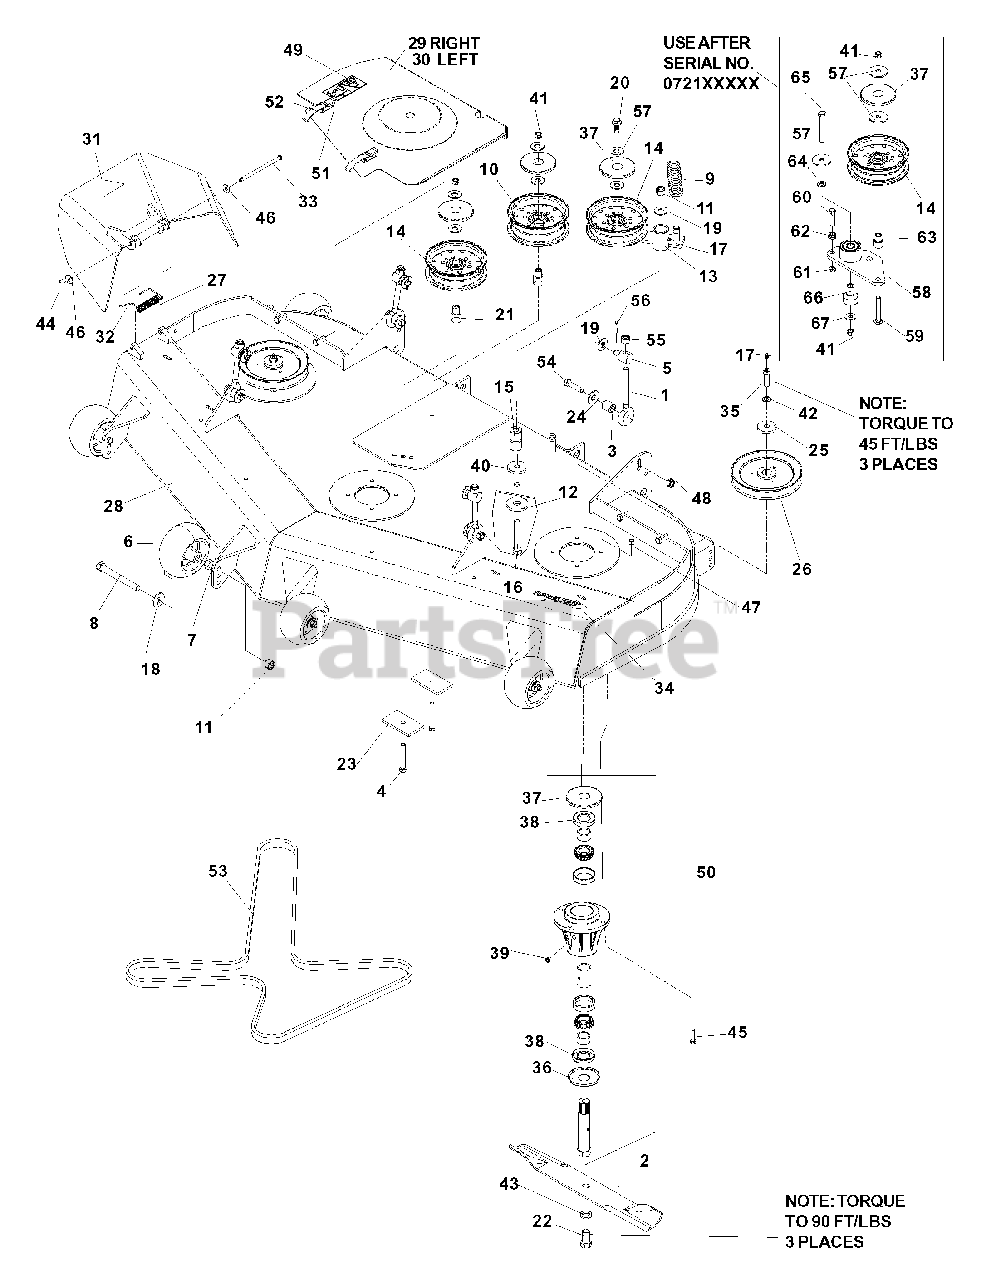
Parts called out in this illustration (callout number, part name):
2	BLADE, 21"
4	HCS, 3/8 -16 x 2 3/4
6	ROLLER, ANTI SCALP
7	NUT, 1/2 -13
8	HHB, 1/2 -13 x 4
9	SPRING, EXTENSION
10	PULLEY, IDLER
11	NUT, 1/2 -13, NYLOC
14	PULLEY, IDLER
15	BUSHING, PIVOT
16	HCS, 1/2 -13 x 3 1/4,
17	ZERK, STRAIGHT,1/4 -28
18	WASHER, 1/2
19	WASHER, 9/16
20	HCS, 3/8 -16 x 1,
21	BUSHING, IDLER
22	HCS, 5/8 -18 x 1 1/4 ,
23	PAD
24	SPRING WASHER,1/2
25	WASHER,469
26	PULLEY
27	CAP-SLEEVE
28	DECK W/DECALS
29	BELT SHIELD, RIGHT
30	BELT SHIELD, LEFT
31	DISCHARGE CHUTE
32	SPRING, TORSION
33	PIN-CLEVIS, 5/16 DIA. x 5.19
34	DECAL, TUNNELRAM
35	HCS, 7/16 -20 x 1/2, GR8, SPEC
36	BOTTOM DUST CAP
37	TOP DUST CAP
38	SHAFT SEAL
39	PLUG, VENTED
40	WASHER, 1/2
41	NUT, 3/8 -16, NYLOC
42	LOCKWASHER, 7/16
43	LOCKWASHER, 5/8
44	PIN COTTER, 1/8 x 3/4
45	HCS, 5/16 -18 x 1 1/4,
46	WASHER, 5/16
47	NUT, 5/16 -18, NYLOC
48	NUT, 7/16 -14, CNTRLCK, GR A
49	DECAL, EURO SEVERING
50	SPINDLE ASSEMBLY
52	DRAW LATCH
54	HCS, 7/16 -14 x 1 3/4
55	NUT, 1/2 -13, NYLOC
56	PIN COTTER, 1/8 x 1
57	WASHER, 3/8 , SPEC
58	ARM, IDLER, W/BEARINGS
59	RHSNB, 3/8 -16 x 2 3/4,
60	HCS, 3/8 -16 x 1 1/2, GR8
61	NUT, 3/8 -16, JAM
62	NUT, 3/8 -16, WHIZLK
63	BUSHING, IDLER
64	WASHER, 3/8 , SAE
65	HCS, 3/8-16 x 3,
66	PIVOT, BEARING
67	WASHER, 3/8
